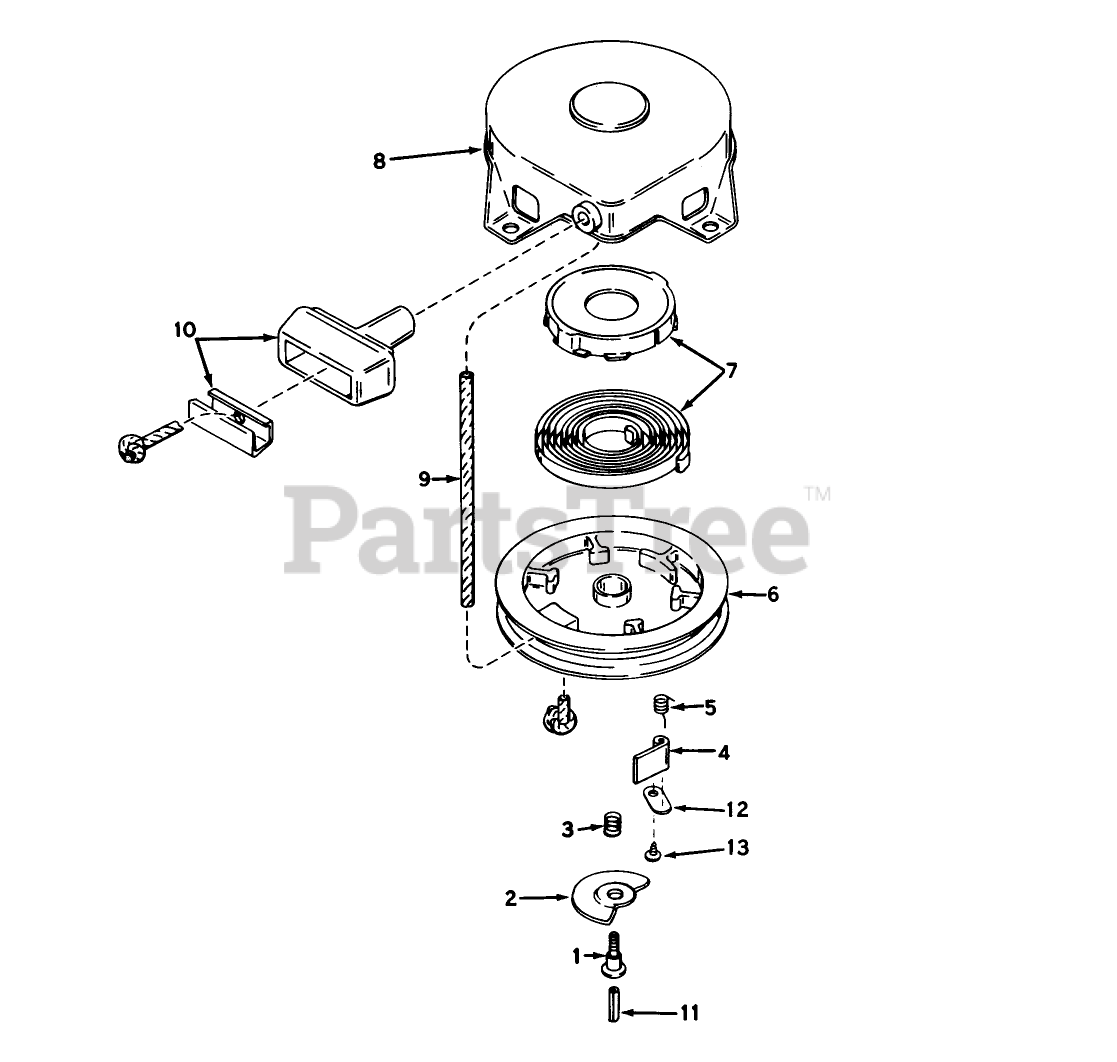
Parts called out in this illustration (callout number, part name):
2	Cam-Dog
3	Spring-Brake
4	Dog-Starter
5	Spring-Dog
7	Spring & Keeper Assy
8	Housing Assy., Starter (Incl. Ref. #1)
9	Rope-Starter
10	Assy., Starter
11	Centering
12	Retainer-Dog
